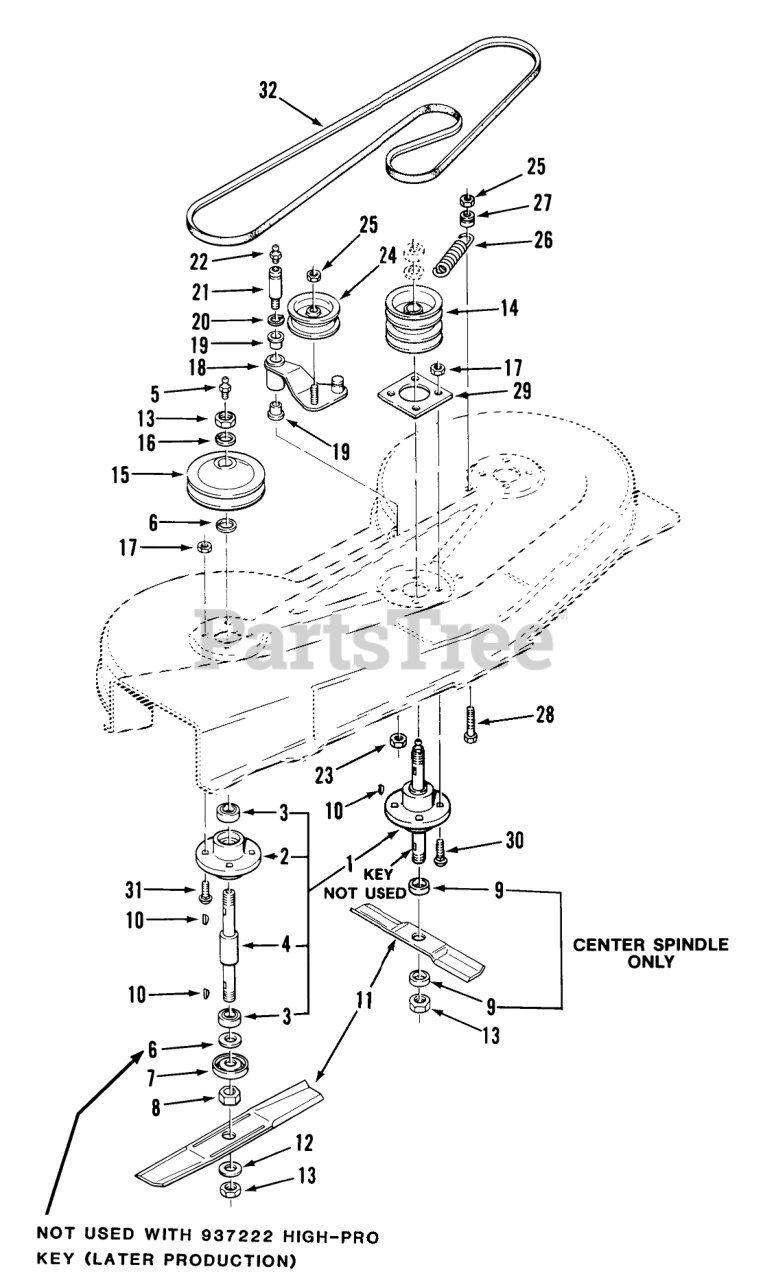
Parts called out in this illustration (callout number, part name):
1	Spindle Assembly
2	Housing
3	BEARING-BALL
4	Spindle (Includes Item 5)
5	Zerk
6	Washer
7	SLINGER BEARING
8	Spacer (Thick)-Right & Left Spindle
9	SPACER-CENTER BLADE
10	KEY WOODRUFF
11	SER ASSY BLADE KIT
14	PULLEY CENTER
15	Pulley-Right & Left Spindle
16	Lockwasher 3/4
17	NUT-HEX, JAM
18	Idler Arm
19	BUSHING
20	SNAP RING- 5/8 EXT
22	Zerk
23	Eslok Nut
24	Flat Idler
25	Nut
26	SPRING EXTENSION
27	Spring Anchor
28	BOLT
29	Plate-Center Spindle
30	Bolt-Carriage
31	CARRIAGE BOLT -9
32	V-BELT
